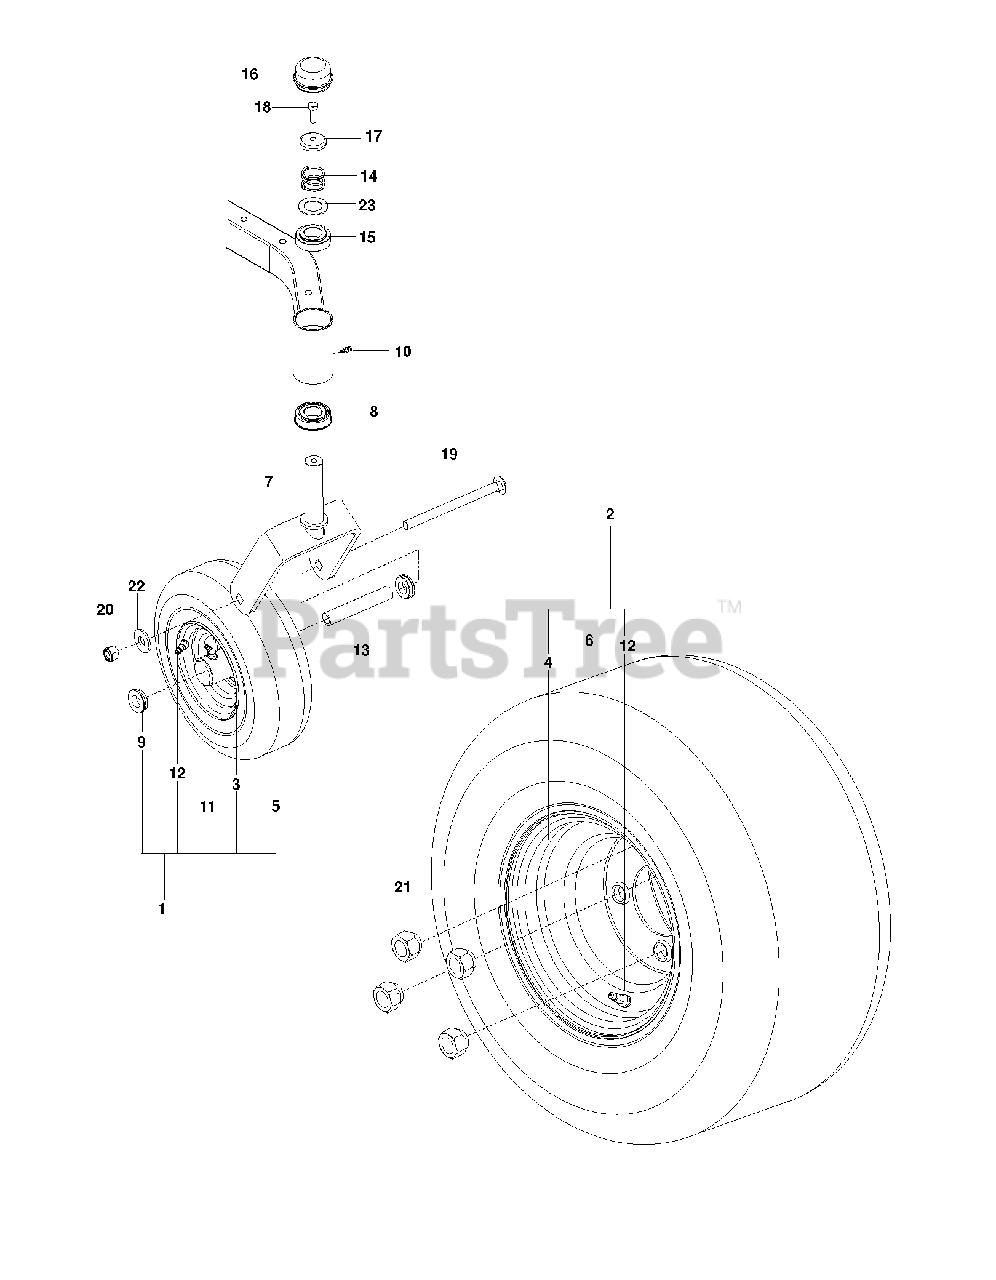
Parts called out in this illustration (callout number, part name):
1	WHEEL ASSY, WIDE, RZ
2	TIRE ASM, 20 X 8-8
4	RIM.8X7.W/8".OFFSET.SILVER.ZTR
5	TIRE.11"X4"-5.4PLY.SMOOTH.KEND
6	TIRE 20 X 8, TURF
7	YOKE.CASTER.ORANGE
8	BEARING FLANGED
9	BUSHING, WHEEL, 3/4"
10	ZERK, 3/16, DRIVE IN
11	ZERK
12	VALVE STEM TR-412
13	SPACER, PIVOT
14	SPRING, CASTER
15	BUSHING, CASTER
16	GREASE CAP
17	CASTER.PLUG
18	5/16-18X1 HHB G5W/NY
19	RHSNB 1/2-13 X 7.5
20	NUT 1/2-13 HEX CNTRLK GR 5 ZD
21	LUG NUT 1/2F
22	WASH USS FLAT 1/2
23	WASHER, 1.025 ID X 1.64
